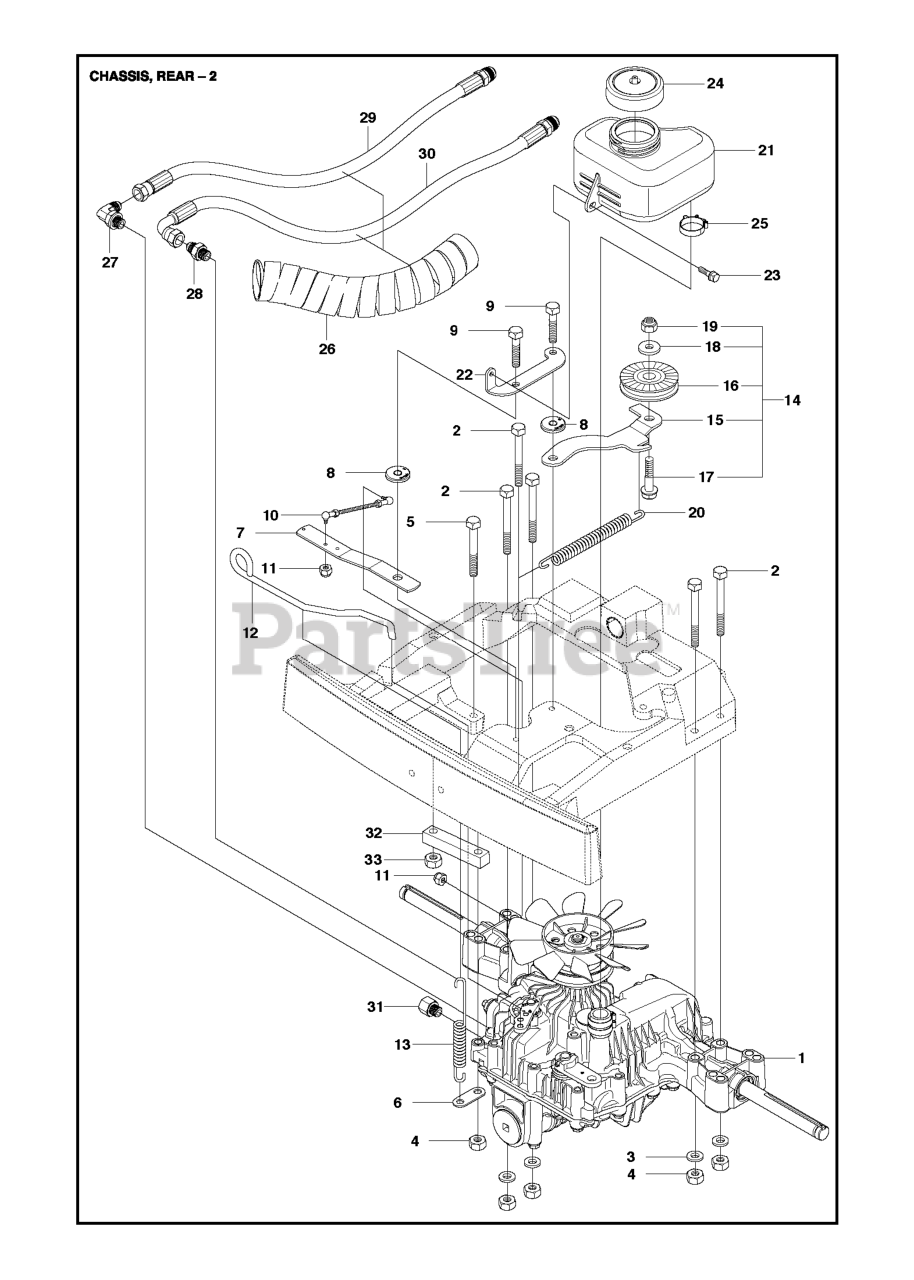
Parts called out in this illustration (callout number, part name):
1	HANDLE ASSY
3	HANDLE HALF (R)
4	SCREW
7	SPRING RUBBER
8	LEVER STOP
12	TRIGGER 848L5W34C0
14	HANDLE HALF (L)
16	SHAFT PIVOT
18	HOLDER, HANDLE
20	HOLDER TH
21	KNOB
31	RP CORD
33	WIRING ASSY 130BT
34	CONTACT SPRING
35	CONTACT SPRING
